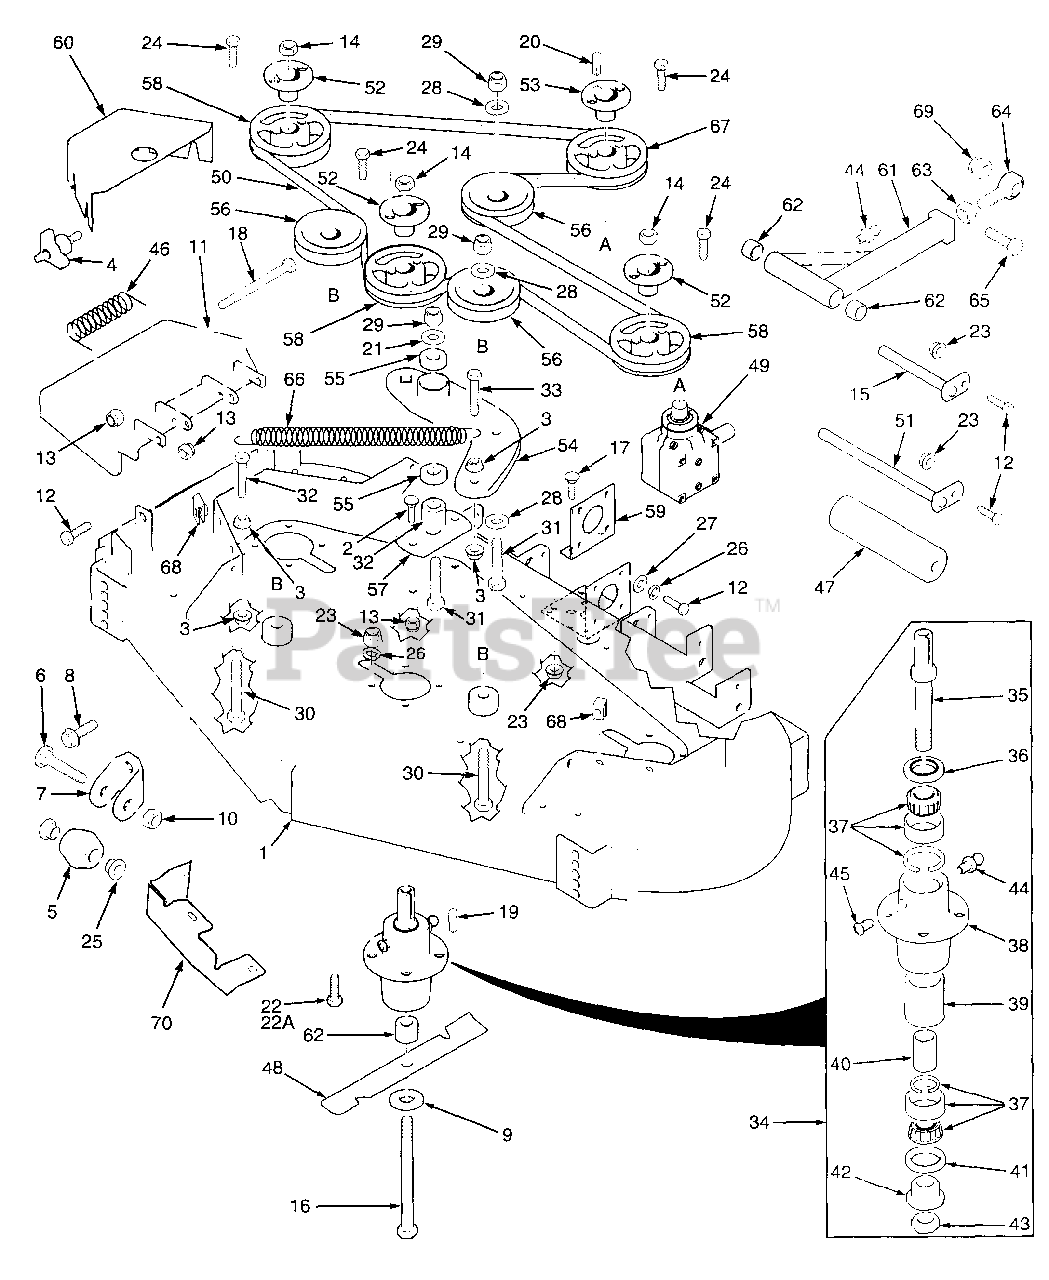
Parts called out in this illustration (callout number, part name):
1	Cutter Deck, 61"
1	Cutter Deck, 61" Advantage
1	Cutter Deck, 72"
1	Cutter Deck, 72" Advantage
2	Bolt, Carriage 5/16-18 x 1"
3	Nut, Hex Serrated Flange 3/8-16
4	Wing Nut, 3/8-16
5	Anti-Scalp Wheel
6	Bolt, Carriage 3/8-16 x 4"
7	Anti-Scalp Wheel Bracket
8	Bolt, Hex Serrated Flange 3/8-16 x 1"
9	Flatwasher, 5/8" (.688 x 1.75 x .134)
10	Locknut, 3/8-16 Center Lock
11	Discharge Chute, 61" & 72"
12	Bolt, Hex Head 5/16-18 x 1.75"
13	Nut, Hex Elastic Stop 5/16-18
14	Nut, 5/8-11 UNC
15	Push Arm Shaft
16	Bolt, Hex Head 5/8-11 x 9.5"
17	Bolt, Carriage 5/16-18 x 3/4"
18	Bolt, Hex Head 5/16-18 x 4-3/4"
19	Key, 1/4 x 1/4 x 2"
20	Key, 1/4 x 1/4 x 1-1/4"
21	Flatwasher, 3/8-.39 x .938 x .105 HD
22	Bolt, Hex Head 5/16-18 x 1.5"
22A	Bolt, Hex Head 5/16-18 x 1.75"
23	Nut, Hex Serrated Flange 5/16-18
24	Bolt, Hex Head 1/2-20 x .75"
25	Bushing, .376 I.D. Oilite
26	Lockwasher, 5/16"
27	Flatwasher, 5/16" (.375 x .875 x .083)
28	Flatwasher, 3/8" (.391 x .938 x .105)
29	Nut, Hex Elastic Stop 3/8-16
30	Bolt, Hex Head 3/8-16 x 3.25"
31	Bolt, Hex Head 3/8-16 x 2.5"
32	Pivot, Idler - Short
33	Bolt, Hex Head 3/8-16 x 1.5" Grade 8
34	Spindle Assembly
35	Spindle Shaft
36	Seal, Top
37	Bearing Assembly
38	Spindle Housing
39	Spacer, Outside
40	Spacer, Inside
41	Seal, Bottom
42	Spindle Bushing, Bottom
43	Nut, Special 1-1/16 - 18
44	Grease Fitting
45	Relief Fitting, Tapered Spindle
46	Spring, Discharge Chute
47	Guide, Roller
48	Cutter Blade, 21.0" 61"
48	Cutter Blade, 24.5" 72"
49	Gearbox Assembly, Deck Drive
50	Belt, Cutter Deck Drive, 61"
50	Belt, Cutter Deck Drive, 72"
51	Roller Shaft
52	Tapered Hub. 1.125" Bore
53	Tapered Hub, 1" Bore
54	Idler Arm, Cutter Deck
55	Bearings, Ball
56	Pulley, Idler
57	Base, idler Pivot
58	Pulley, 6.35 O.D. - 61"
59	Mounting Plate. Gearbox
60	Belt Cover, LH - 61"
61	Pusharm
62	Spacer, Spindle
63	Nut, Hex Head 5/8-18 UNF
64	Rod End, 5/8" Male RH Thread
65	Bolt, Hex Head 5/8-11 x 4.5"
66	Spring, Cutter Deck
67	Pulley, 6.35 O.D. - 61"
68	U-Nut, 3/8-16
69	Nut, Hex Elastic Stop 5/8-11
70	Discharge Baffle 61"
